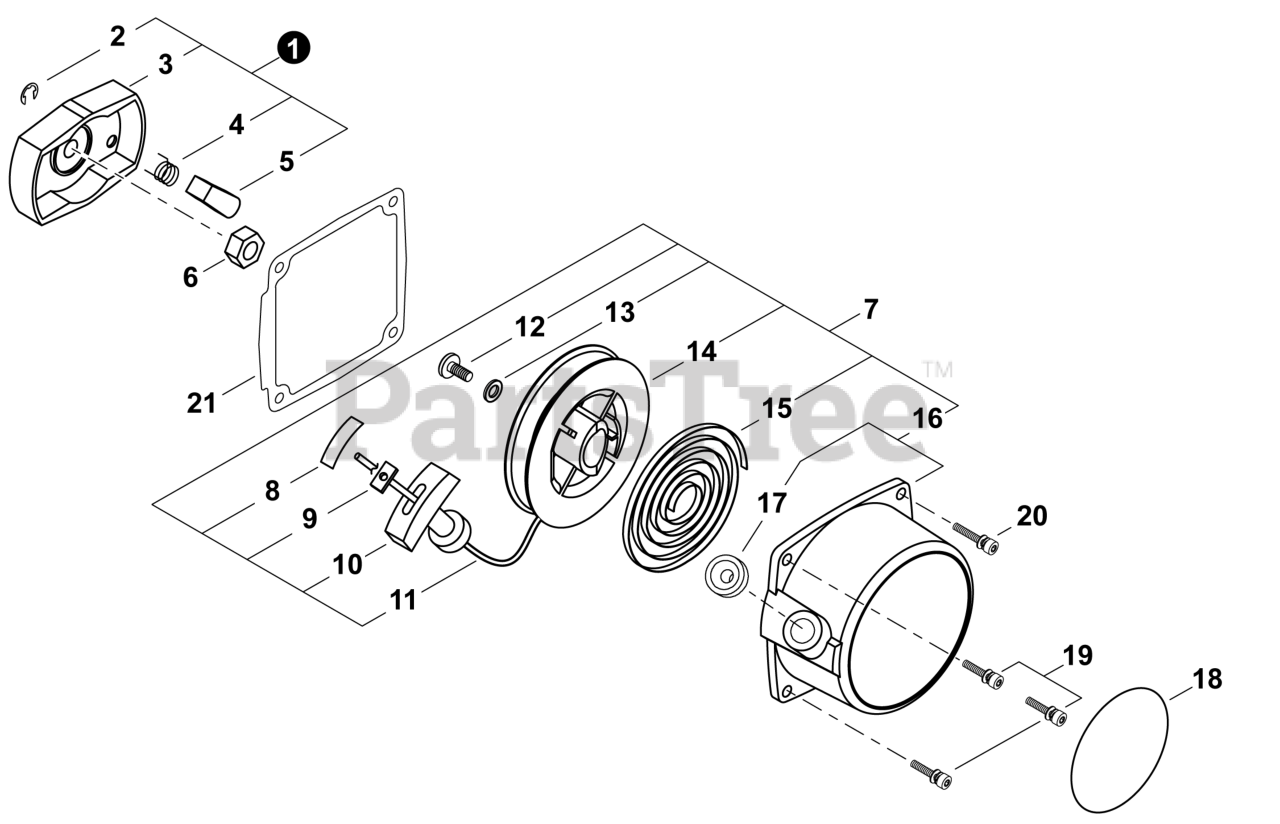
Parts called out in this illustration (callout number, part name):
1	PAWL ASSY, STARTER
2	E-RING 4
3	PULLEY, STARTER
4	SPRING, RETURN
5	PAWL, STARTER
6	NUT M8xH5
7	STARTER ASSY, RECOIL
9	RETAINER, ROPE
10	GRIP, STARTER
11	ROPE, STARTER
14	REEL, ROPE
15	SPRING, RECOIL
16	CASE, RECOIL STARTER
17	GUIDE, ROPE
18	LABEL - RECOIL STARTER
19	BOLT M4x16
20	BOLT M4x20
21	GASKET, RECOIL STARTER
